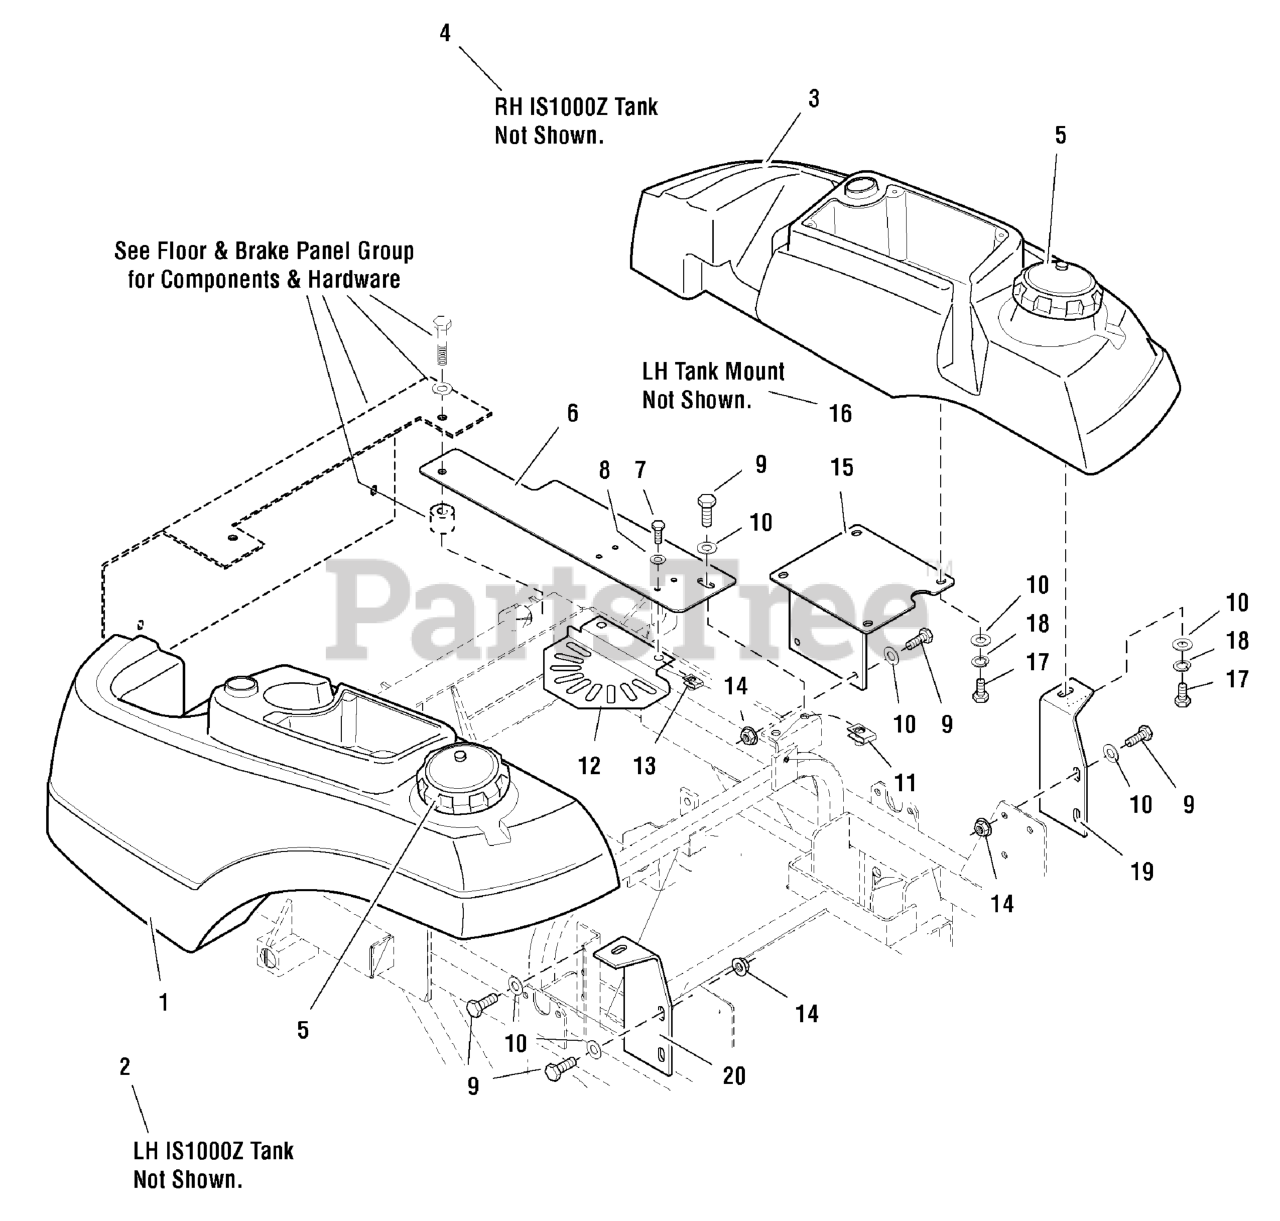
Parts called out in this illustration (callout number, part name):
1	FUEL TANK, 1000Z, LH
3	FUEL TANK, 1000Z, RH
5	CAP, FUEL TANK, 3-1/2 NECK
6	COVER, Fan Shield Mount
7	BOLT, 1/4-20 x 3/4
8	WASHER, 1/4 SAE
9	BOLT, 5/16-18 X 1 GD5 YZ
10	WASHER, 5/16" SAE
11	BODY CLIP, 5/16-18-7GA MATERIAL
12	FAN SHIELD
13	BODY CLIP, 1/4-20
14	NUT, 5/16-18 HEX SERRATED FLANGE (SMALL)
15	FUEL TANK MOUNT-RH
17	BOLT, 5/16-18 X 3/4 GD5
18	WASHER, 5/16 LOCK CZ
19	BRACKET, Fuel Tank Support-RH
20	BRACKET, Fuel Tank Support-LH
